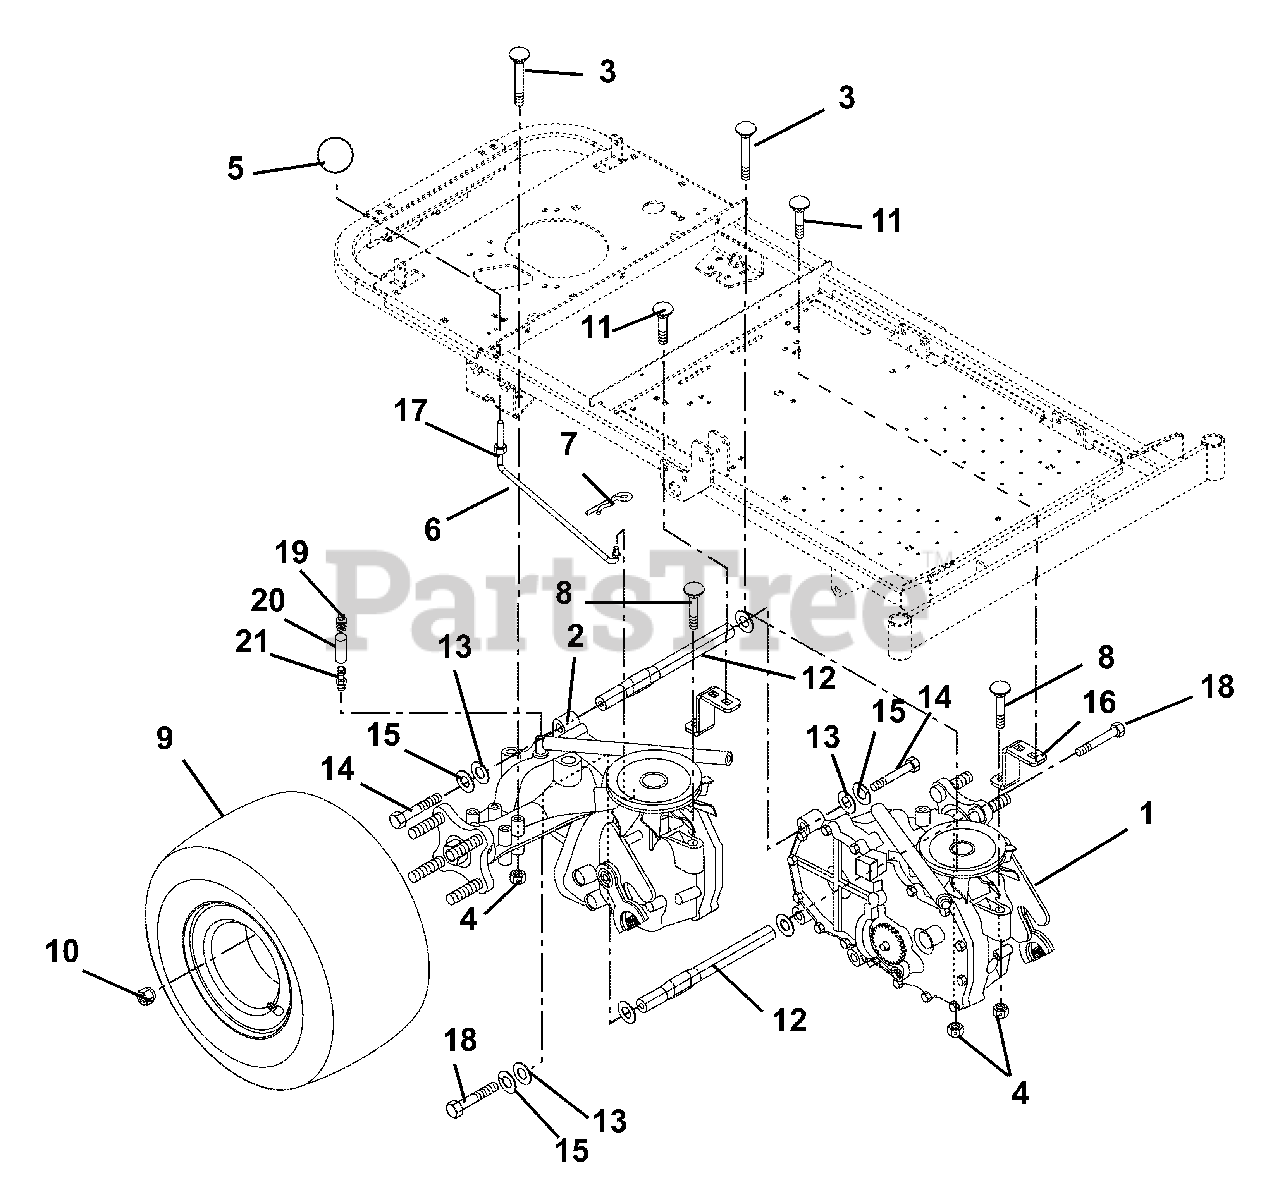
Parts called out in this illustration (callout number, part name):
1	EZT, Left Hand Transaxle-Hydrogear
2	EZT, Right Hand Transaxle-Hydrogear
3	Bolt-Round Head Square Neck .31-18 x 2.75
4	Nut 5/16-18 Flange Nyloc
6	Rod, Dump EZT
7	Pin, Hair
8	Bolt, Round Head Square Neck .31-18 x 2.25
9	Assembly, Tire 8.5 x 18 2 Ply
10	Nut, Lug .50-20
11	Bolt, Round Head Square Neck .31-18 x 1.00 Grade 5
13	Washer, Flat Steel .344 x .688 x .065
14	Bolt, Hex .31-18 x 2.50 Grade 5
15	Washer, Locking .31 x .078 Regular
16	Strap, Torque
17	Nut-Hex .25-20
18	Bolt-Hex .31-18 x 2.00 Grade 5
19	Cap, Vent .50
20	Hose, Vent
21	Fitting, Straight .50
